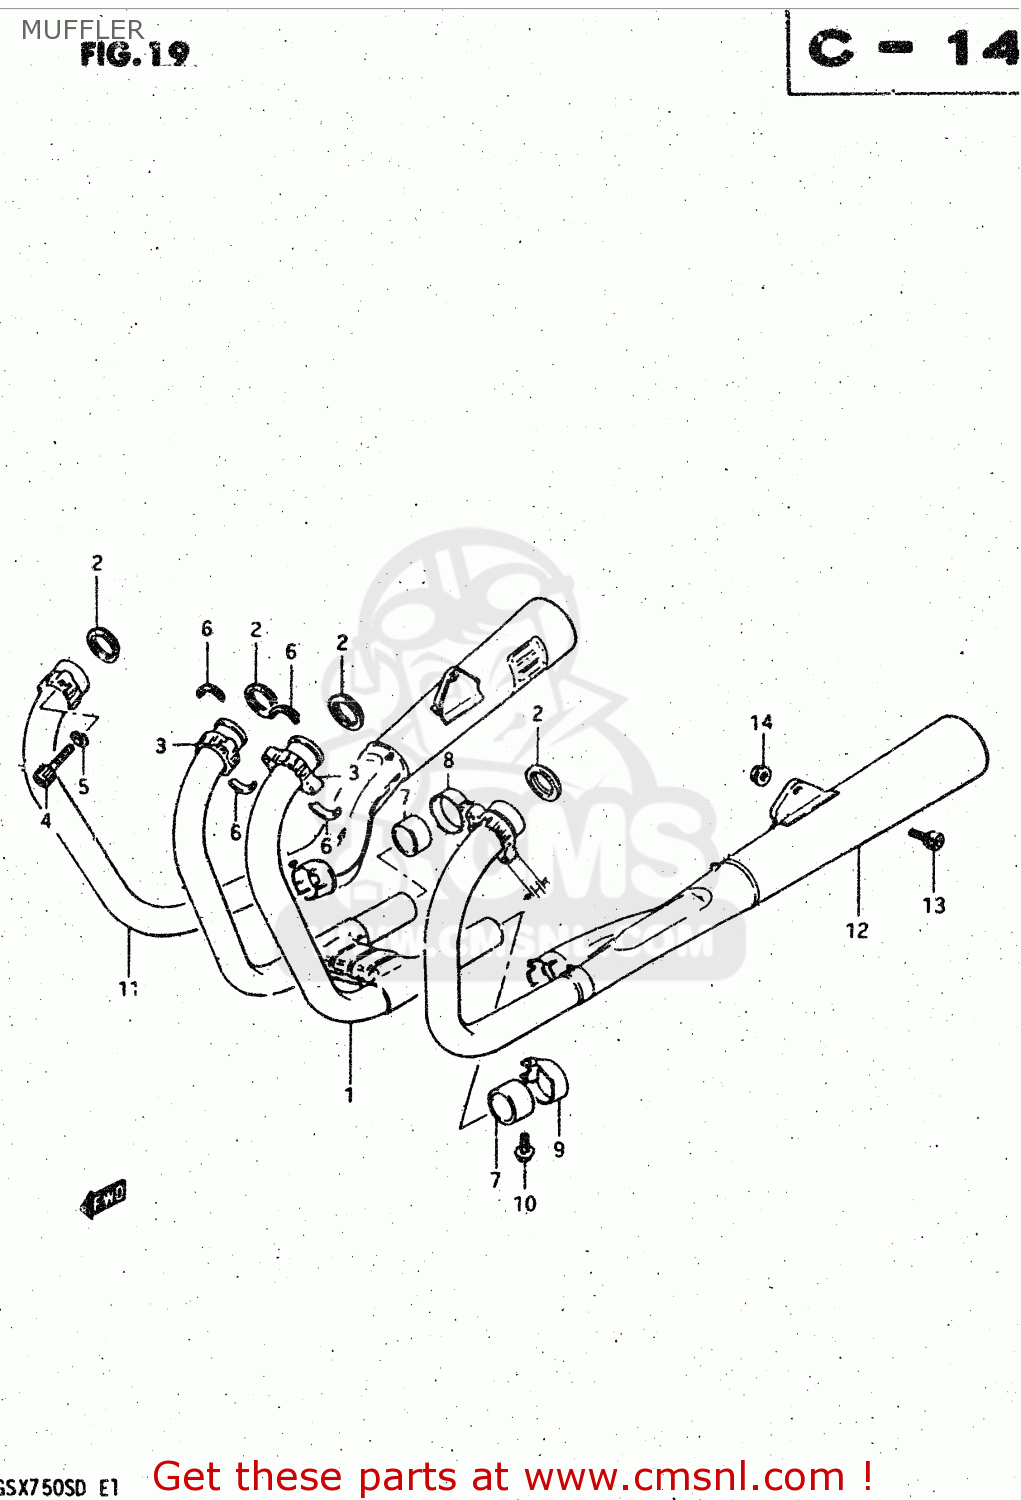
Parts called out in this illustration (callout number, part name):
1	PIPE,EXHAUST
2	GASKET,EXHAUST PIPE (NAS)
3	CLAMP(H:21)
4	BOLT
5	LOCK WASHER
6	PLATE,EXHAUST P
7	CONNECTOR,MUFFLER
8	CLAMP,MUFFLER CONNECTOR,R
9	CLAMP,MUFFLER CONNECTOR,L
10	BOLT
11	MUFFLER, RH (H:21)
12	MUFFLER, LH (H:21)
13	BOLT
14	NUT
